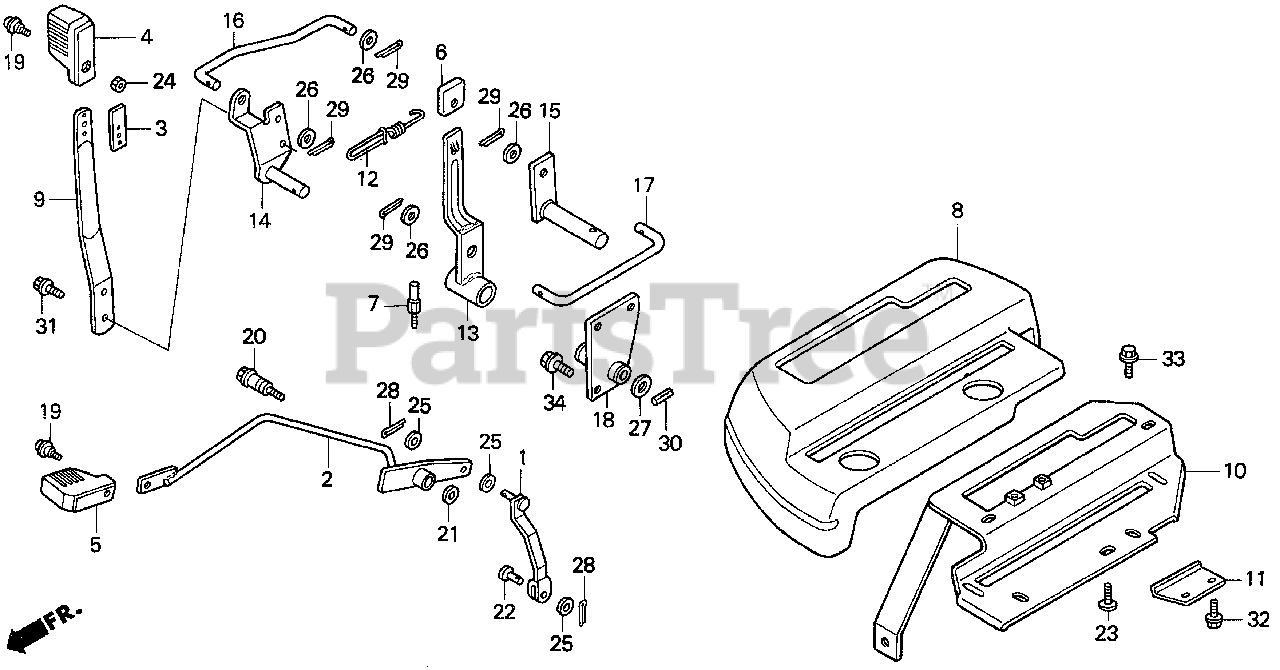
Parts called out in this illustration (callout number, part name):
1	ROD, CHANGE (2/4WD)
2	LEVER, CHANGE (2/4WD)
3	PLATE, P.T.O. SHIFT LEVER
4	KNOB, CHANGE LEVER
5	KNOB B, CHANGE LEVER *YR161* (ORANGE)
6	GRIP, ADJUSTER
7	BOLT, STOPPER
8	PANEL, R. CONTROL *R165* (JOLLY RED)
9	LEVER, HYDRAULIC CONTROL
10	GUIDE, HYDRAULIC CONTROL LEVER
11	PLATE, TWO MOTION
12	SPRING, CONTROL LEVER RETURN
13	LEVER, ROTARY VALVE
14	SHAFT, HYDRAULIC CONTROL
15	ARM, ROTARY VALVE
16	JOINT, HYDRAULIC CONTROL
17	JOINT, ROTARY VALVE
18	BASE, HYDRAULIC CONTROL
19	SCREW, HINGE PATCH
20	BOLT, CHANGE PIVOT
21	WASHER, PLAIN (8X23X3.2)
22	PIN, P.T.O. CHANGE ROD
23	SCREW, TAPPING (6X12)
24	NUT, HEX. (5MM)
25	WASHER, PLAIN (6MM)
26	WASHER, PLAIN (8MM)
27	WASHER, FLAT (12MM)
28	PIN, COTTER (1.6X25)
29	PIN, COTTER (2.5MM)
30	PIN, SPRING (4X20)
31	BOLT, FLANGE (6X10)
32	BOLT, FLANGE (6X12)
33	BOLT, FLANGE (8X12)
34	BOLT, FLANGE (8X14)
